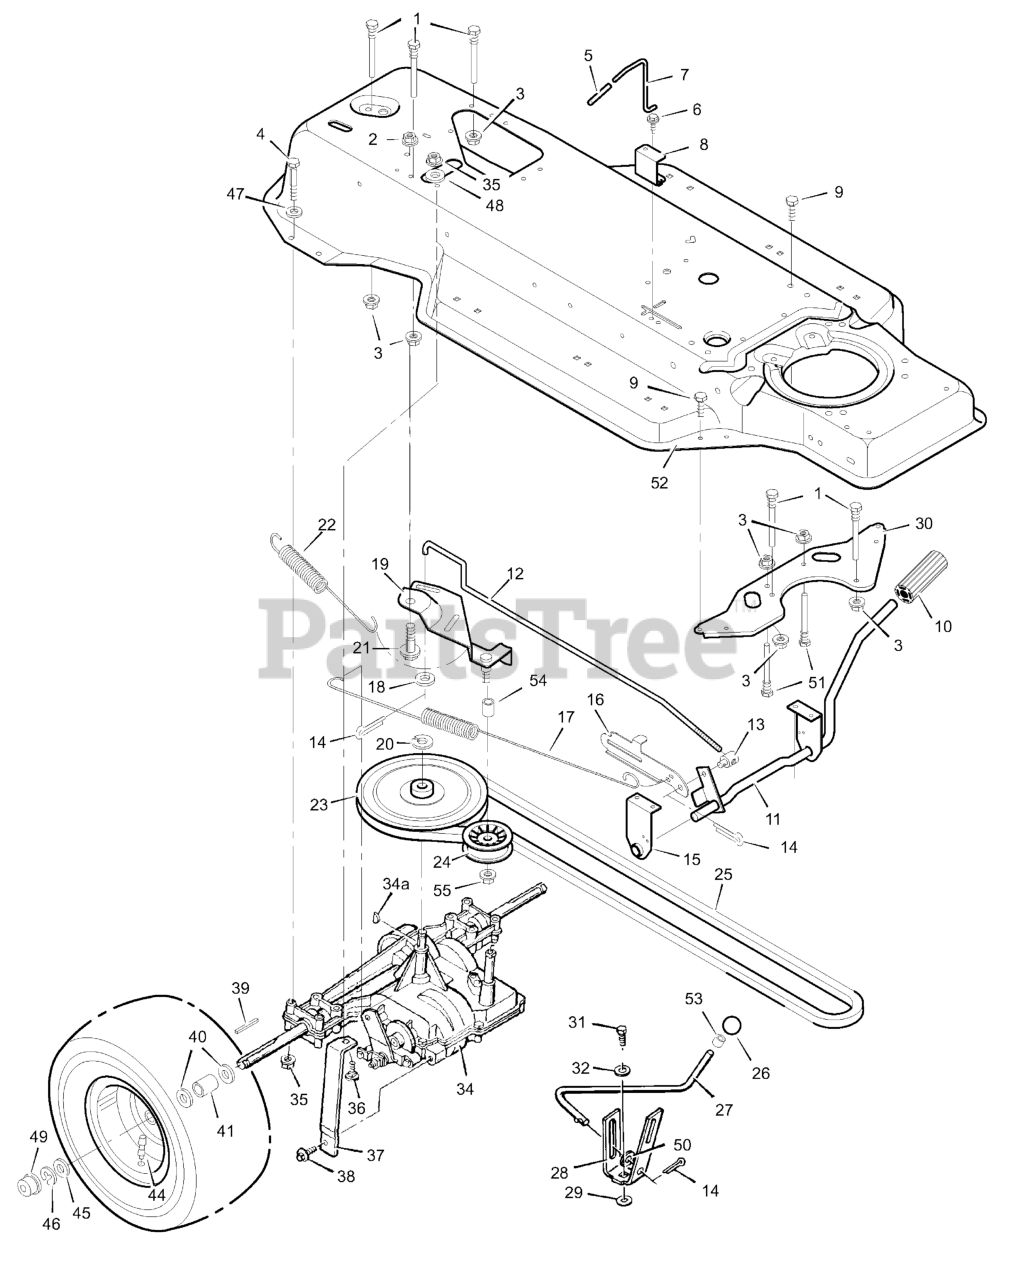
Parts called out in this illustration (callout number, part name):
1	Guide, Belt
2	Locknut, Flange
3	Nut, Flange
4	Bolt, Hex
7	Rod, Control
8	Guide, Bracket
10	Clutch and Brake Pedal
11	Lever Assembly
12	Rod, Clutch
13	Nut, Adjustable
14	Pin, Cotter
15	Bracket, Support
16	Latch, Park Brake
17	Spring, Brake Extension
18	Washer
19	Bracket Assembly, Idler
20	Ring, Retainer
21	Bolt, Shoulder
22	Spring, Drive Extension
23	Pulley, Motion Drive
24	Pulley, Backside Idler
25	Belt, Motion Drive
26	Knob, Shift Lever
27	Lever, Shift
28	Yoke, Shift
30	Plate, Belt Guide
31	Bolt, Hex
32	Lockwasher
34	Transaxle, Peerless **
34A	Woodruff Key No. 9
35	Nut, Flange
36	Bolt, Carriage
37	Support, Transaxle
39	Key, Square
41	Spacer, Transaxle
43	Wheel & Tire Assembly
44	Stem, Valve
47	Washer
49	Hub Cap
50	Washer
51	Guide, Belt
52	Frame Assembly
53	Ring, Tolerance
55	Nut
